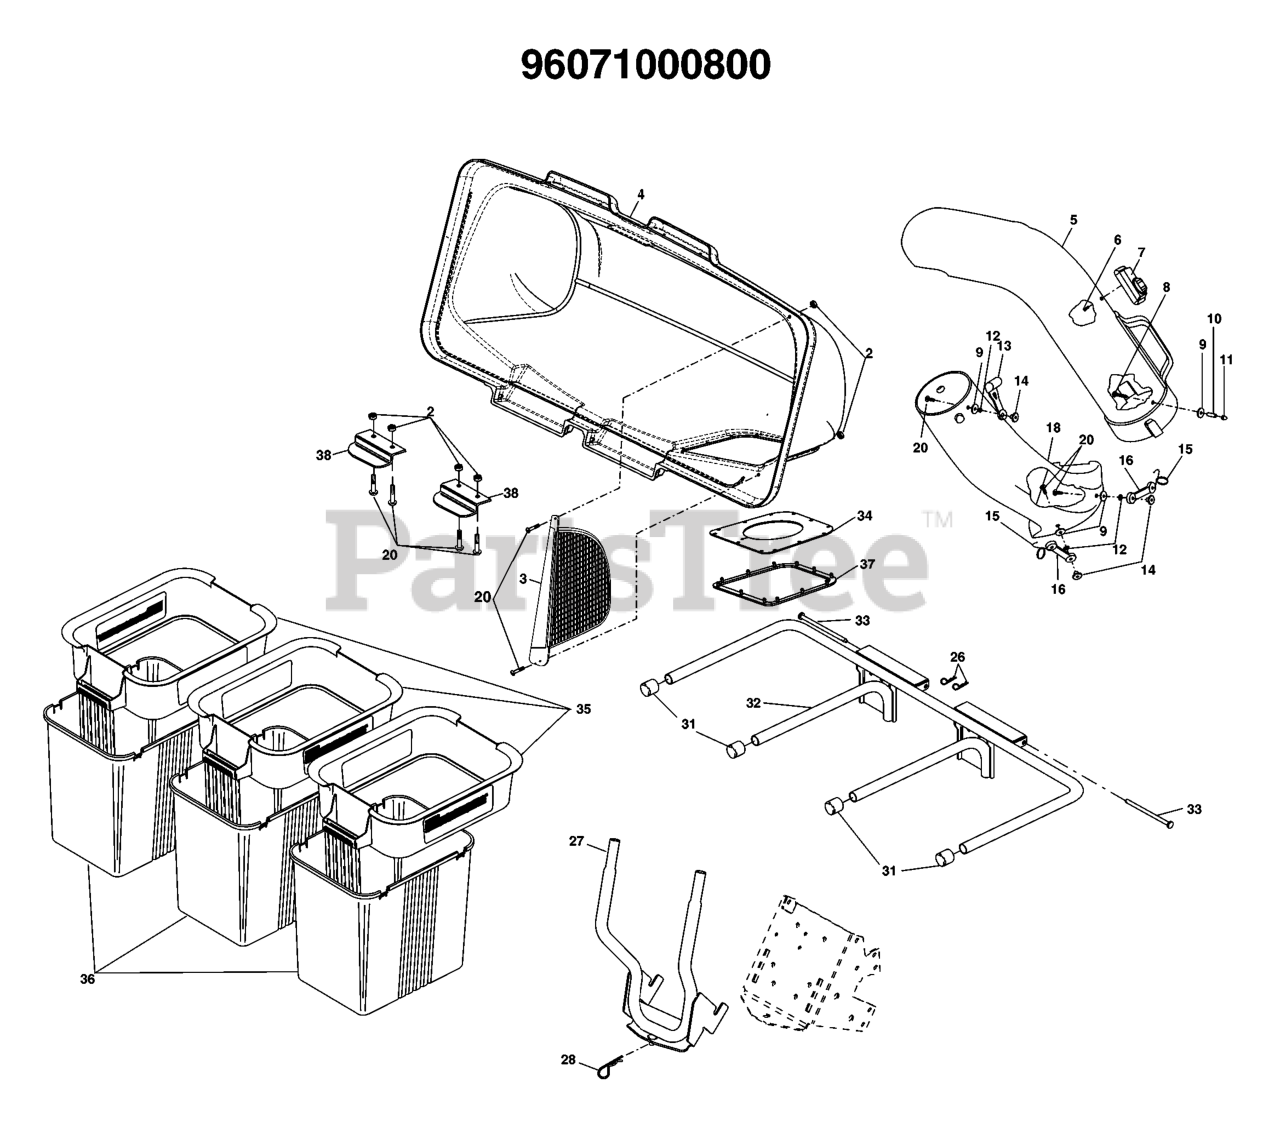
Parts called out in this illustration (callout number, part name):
3	SCREEN.COVER.BAGGER
4	COVER.ASM.3BIN.GENERIC.
5	CHUTE.BAGGER.UPPER.48
7	INDICATOR ASM BAG
8	SCREW
11	NUT
12	LOCKWASHER #10
13	LATCH.HOOD.
14	WELDNUT
15	HOOK LATCH
16	RUBBER LATCH
18	CHUTE.BAGGER.LOWER.48"
20	SCREW
26	RETAINER-SPRNG RB
27	BAGGER FRAME ASSEMBLY
28	SPRING.RETAINER.YELLOW.ZINC
31	PLUG, TUBING END
32	BAGGER.ASM.FRAME.3BIN.BLACK
33	BAGGER.HINGE.PIN
34	SEAL.BAGGER.TOP.3-BIN.BLK
35	CONTAINER TOP
36	CONTAINER BOTTOM
37	GASKET.COVER.BAGGER
38	LATCH CER38
